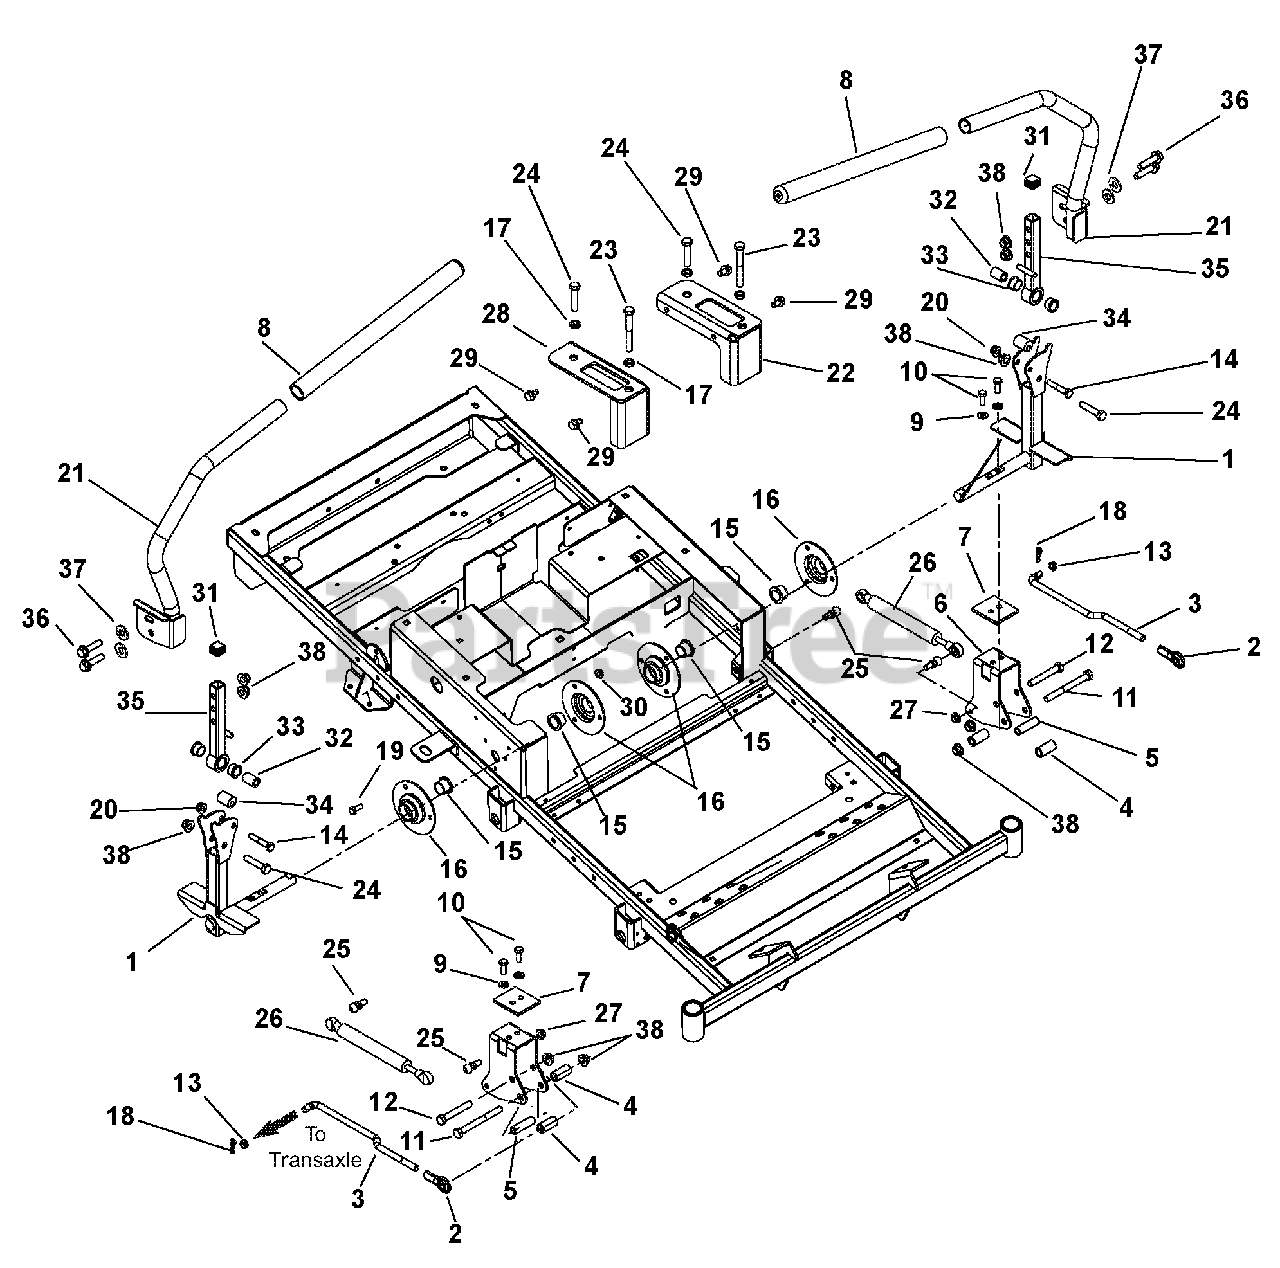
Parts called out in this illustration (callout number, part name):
1	WMT, CONTROL ARM
2	ROD END, .38 RH
3	LINK, TRANSMISSION
4	BSHG, SPCR .390X.625X1.25 PM
5	SPACER, STEERING
6	BRKT, STEERING
7	PLATE, STEERING REINFORCING
8	GRIP, HANDLEBAR 15" FOAM
9	WSHR-LK .31X.078 REG YWZC
10	BLT-HEX .31-18X1.00 GR8 YWZC
11	BLT-HEX .38-16X3.75 GR5 YWZC
12	BLT-HEX .38-16X2.50 GR5 YWZC
13	BUSHING, POLYLINER-.38 SNAPIN
14	BLT-HEX .31-18X1.75 GR5 YWZC
15	BSHG-FLG .750X1.000X.625X1.250
16	BEARING FLANGE
17	NUT-HEX-JAM .375-16 YWZC
18	PIN-HAIR INT .08X.18X1.18 YWZC
19	BLT-HEX .25-20X.75 GR5 YWZC
20	NUT-LK-NYL-FLG .31-18 YWZC
21	WMT, STEERING HANDLE RH
22	BRACKET, LH SPEED CONTROL
23	BLT-HEX .38-16X3.00 GR5 FTH YZ
24	BLT-HEX .375-16X1.750 FTD YWZC
25	STUD- BALL
26	DAMPER, CONTROL
27	NUT-LK-TOP-FLG .31-18 YWZC
28	BRACKET, RH SPEED CONTROL
29	SCR-TAP .31-18X.50 HWH TR YWZ
30	NUT-LK-TOP-FLG .25-20 YWZC
31	CAP PLUG, SQ 3/4-14-20 RIBBED
32	SPACER, .375X.625X.970 (PM)
33	BSHG-FLG, .625X.75X.450X.875
34	BSHG, ECCENTRIC .328X.750X.970
35	WMT, UPPER CONTROL ARM
36	BLT-SERHFWH .375-16X1.25 YWZC
37	WSHR-FL-STL.406X.812X.065 YWZ
38	NUT-LK-CTR-JAM .375-16 YWZC
